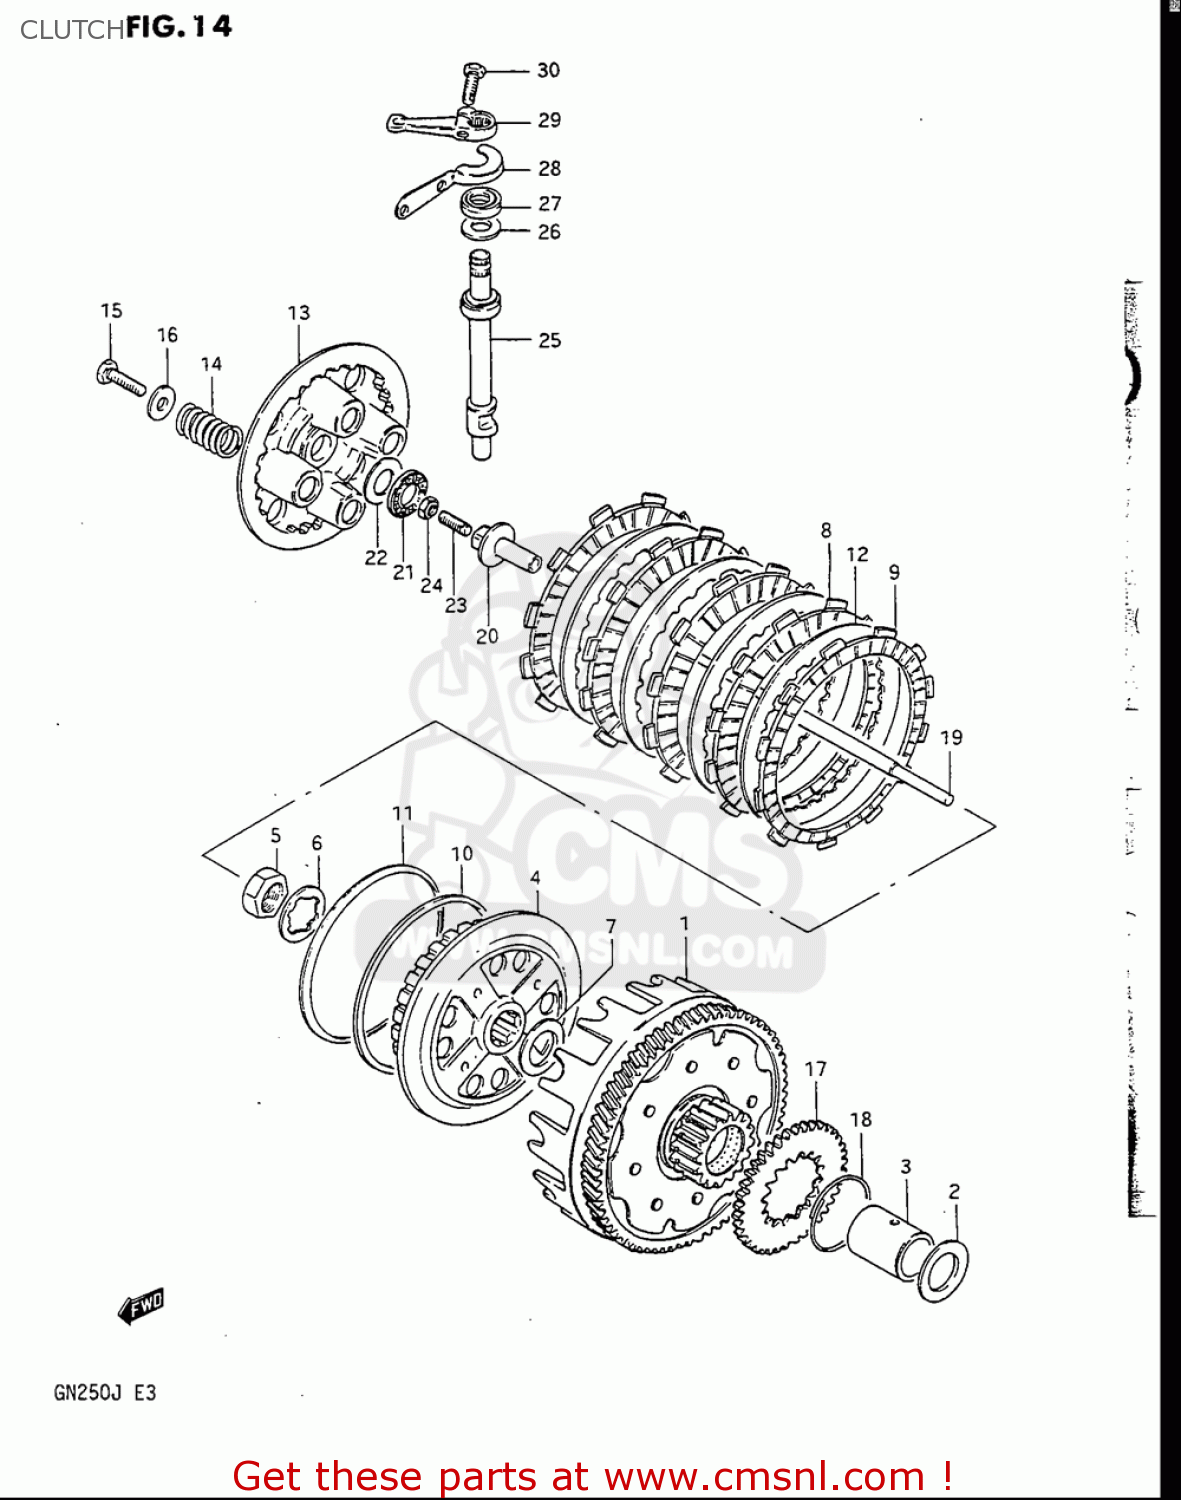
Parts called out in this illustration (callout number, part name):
1	GEAR ASSY,PRI DRIVEN
2	WASHER
3	SPACER(22X28X37.5)
4	HUB,CLUTCH SLEEVE
5	NUT
6	WASHER,LOCK
7	WASHER
8	PLATE,CLUTCH DRIVE (NAS)
9	PLATE,CLUTCH DRIVE(T:3.5) (NAS)
10	SEAT,WAVE WASHER(T:1.4)
11	WASHER
12	PLATE,CLUTCH DRIVEN(T:1.6) (NAS)
13	DISC,CLUTCH PRESSURE
14	SPRING
15	BOLT
16	WASHER(6.5X20X1.6)
17	GEAR,OIL PUMP DRIVE
18	CIRCLIP
19	ROD,CLUTCH PUSH
20	PIECE,CLUTCH PUSH
21	BEARING(15X28X2)
22	WASHER(15.5X28X1)
23	SCREW(6X25)
24	NUT
25	CAMSHAFT,CLUTCH RELEASE
26	WASHER(14.5X22X1)
27	SEAL,OIL (12X22X9)
28	PLATE,CLUTCH RRS CAMSHAFT SEAL
29	ARM,CLUTCH RELEASE
30	BOLT
